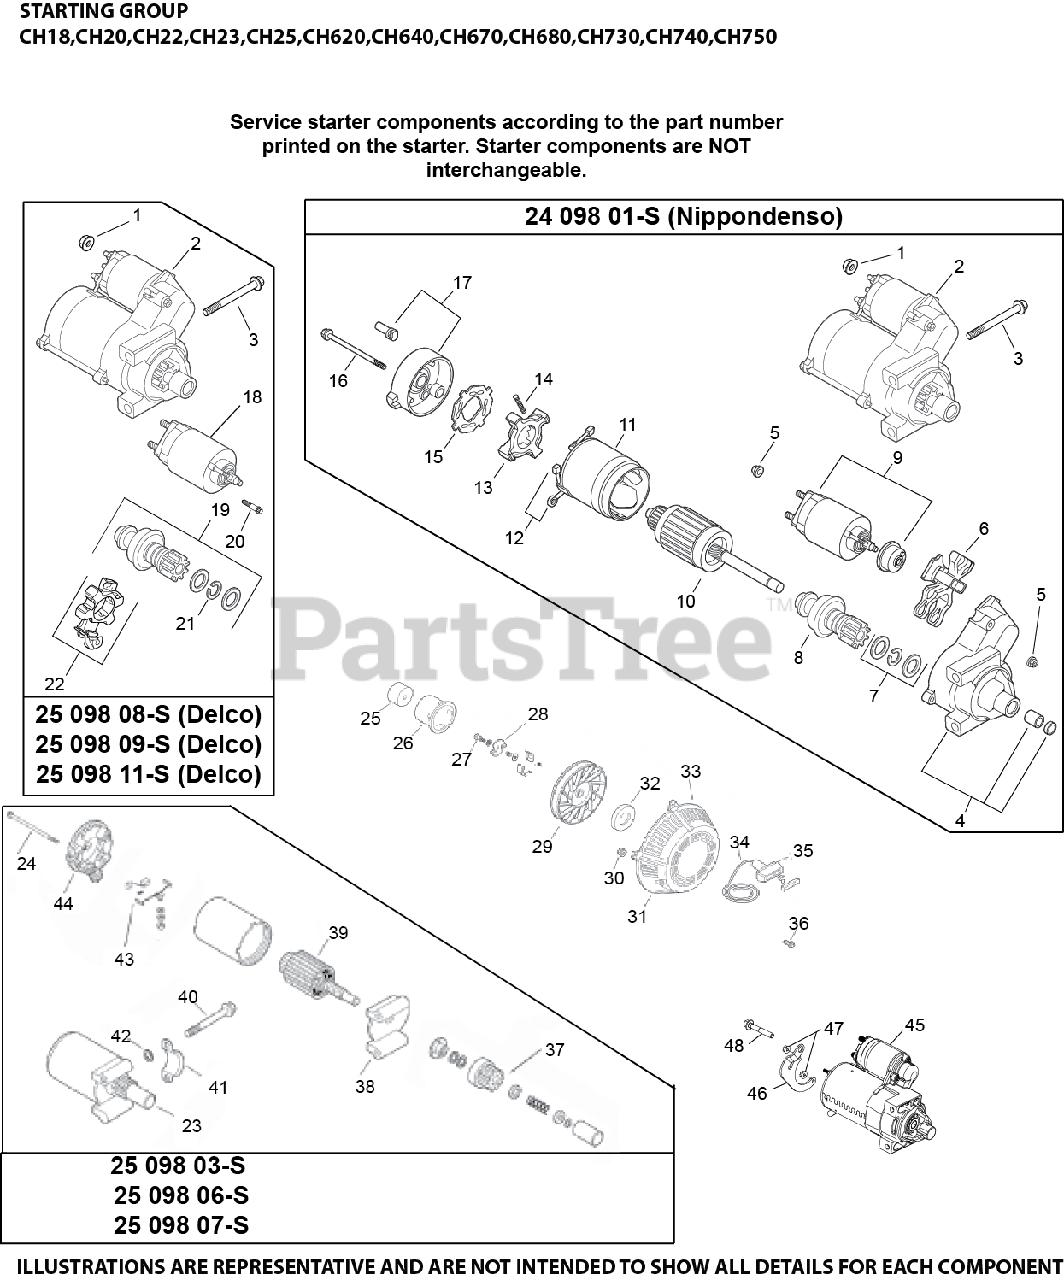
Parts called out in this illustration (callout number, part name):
1	NUT, FLG M8X1.25
2	ELECTRIC STARTER - SOLENOID SHIFT USE 25 098 20-s
3	SCREW - USE M-851080-S
18	KIT, SOLENOID
19	KIT, STARTER PINION
20	SCREW, EXTERNAL TORX HEAD
21	RING, RETAINING
22	KIT, BRUSH HOLDER
